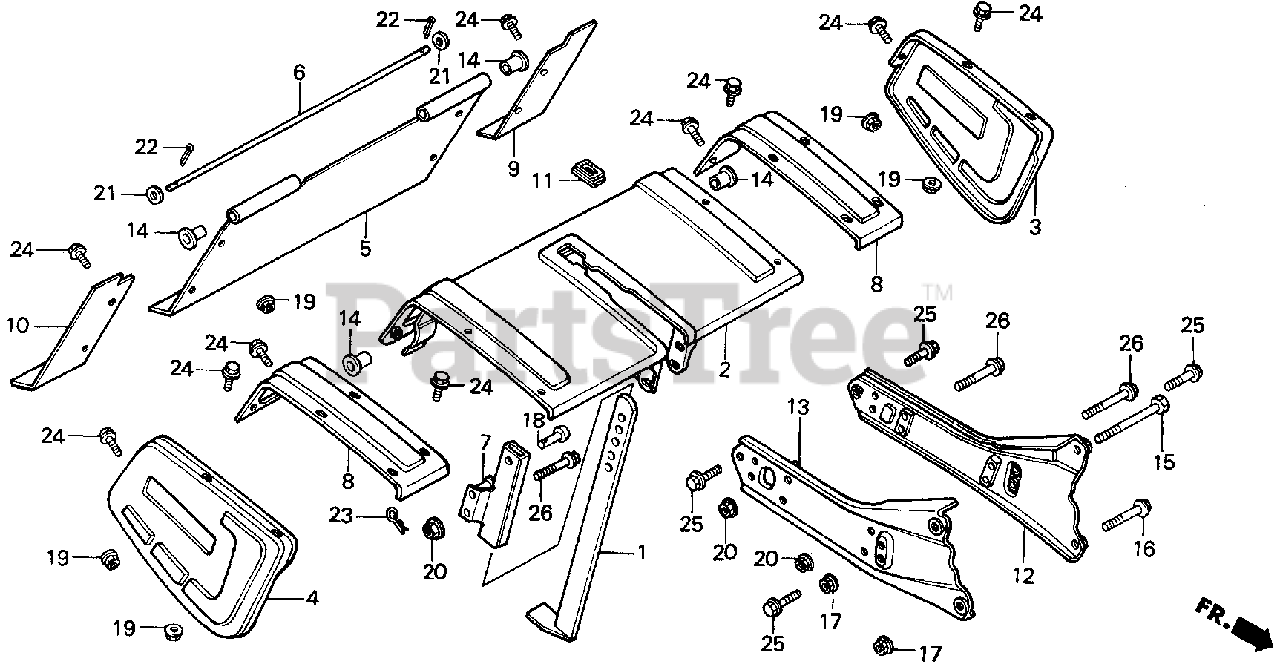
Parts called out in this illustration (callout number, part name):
2	COVER, ROTARY
3	COVER, L. ROTARY
4	COVER, R. ROTARY
5	SPLASH GUARD
6	SHAFT, SPLASH GUARD
7	HOLDER, DRAG BAR
8	COVER, ROTARY EXTENSION
9	SPLASH GUARD, L. EXTENSION
10	SPLASH GUARD, R. EXTENSION
11	GROMMET, COVER
12	FRAME, L. ROTARY
13	FRAME, R. ROTARY
14	BUSH, DISCHARGE GUARD
15	BOLT, HEX. (8X85)
16	BOLT, HEX. (8X50)
17	NUT, FLANGE (8MM)
18	PIN (10X30)
19	NUT, FLANGE (6MM)
20	NUT, FLANGE (8MM)
21	WASHER, PLAIN (6MM)
22	PIN, COTTER (2.5MM)
23	PIN, LOCK (10MM)
24	BOLT, FLANGE (6X10)
25	BOLT, FLANGE (8X16)
26	BOLT, FLANGE (8X50)
